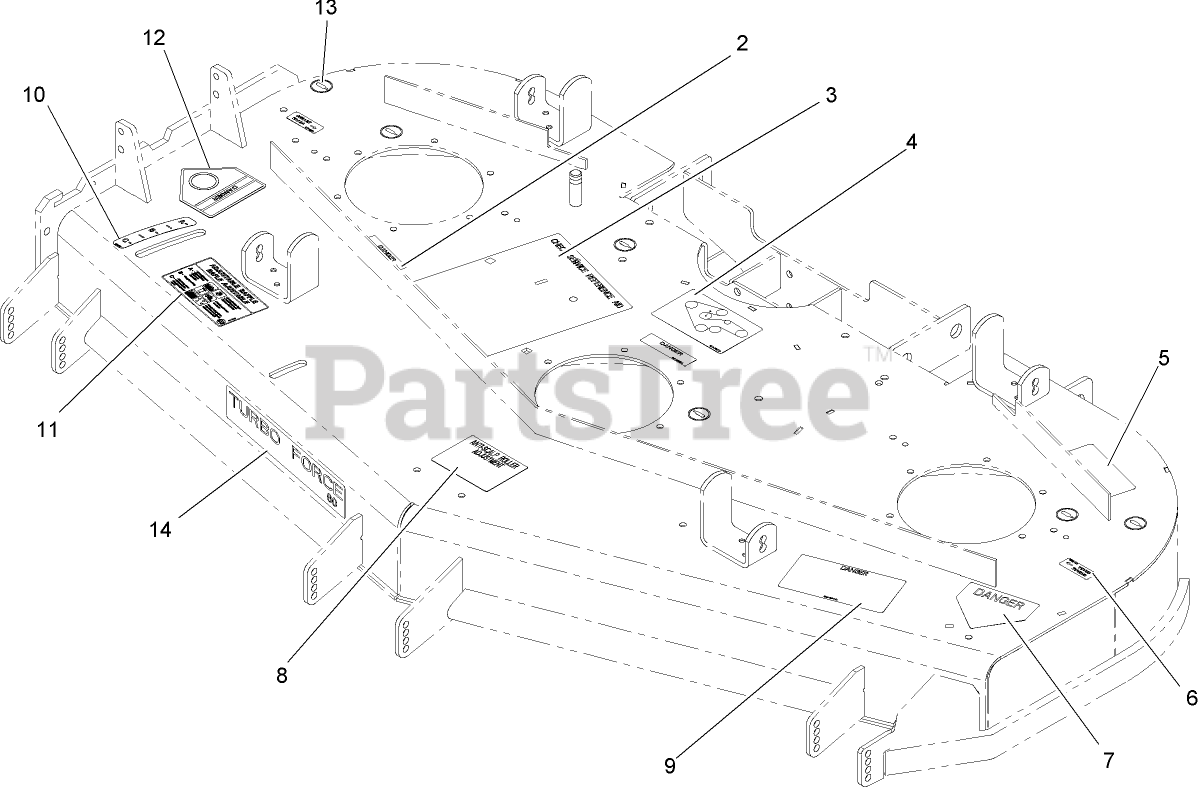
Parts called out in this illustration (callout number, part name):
2	DECAL-COVER, MISSING
3	DECAL-CHECK, SERVICE
4	DECAL-ROUTING, BELT
5	DECAL-TORQUE
6	Decal-Grease
7	DECAL-DANGER
8	DECAL-SCALP, ANTI
9	DECAL-DANGER, THROWN OBJECT
10	DECAL-ADJUSTMENT, BAFFLE
11	DECAL-SETTING, BAFFLE
12	DECAL-DANGER
13	DECAL-GREASE
